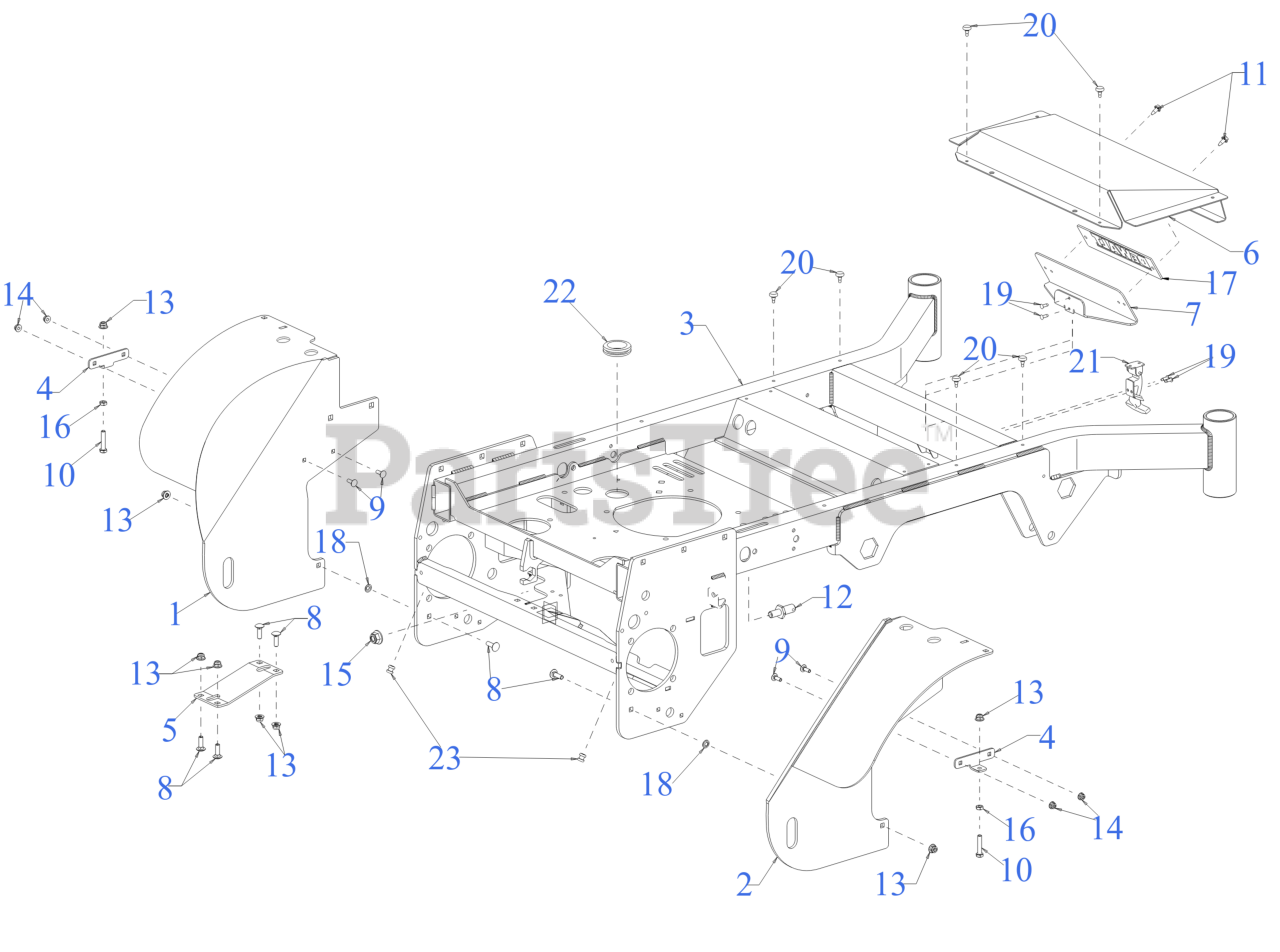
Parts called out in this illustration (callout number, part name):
1	FENDER (LH)
2	FENDER (RH)
3	FRAME
4	BRAKE SPRING BRACKET (RH)
5	SUPPORT BRACKET
6	STAND ON COVER (FRONT)
7	BACK PLATE
8	CARRIAGE BOLT 5/16-18 x 1.00
9	SCREW 1/4-20 x .75 GR5
10	SCREW 5/16-18 x 1.5 LG
11	SCREW 1/4-20X.625
13	FLANGE LOCK NUT 5/16-18
14	FLANGE LOCK NUT
16	HEX NUT
17	DEWALT LOGO (DIE CAST)
18	PUSH NUT
19	POP RIVET
20	RUBBER BUMPER
21	HOOD LATCH ASSEMBLY
22	RUBBER GROMMET (1.50X2.13X.563)
23	GROMMENT
